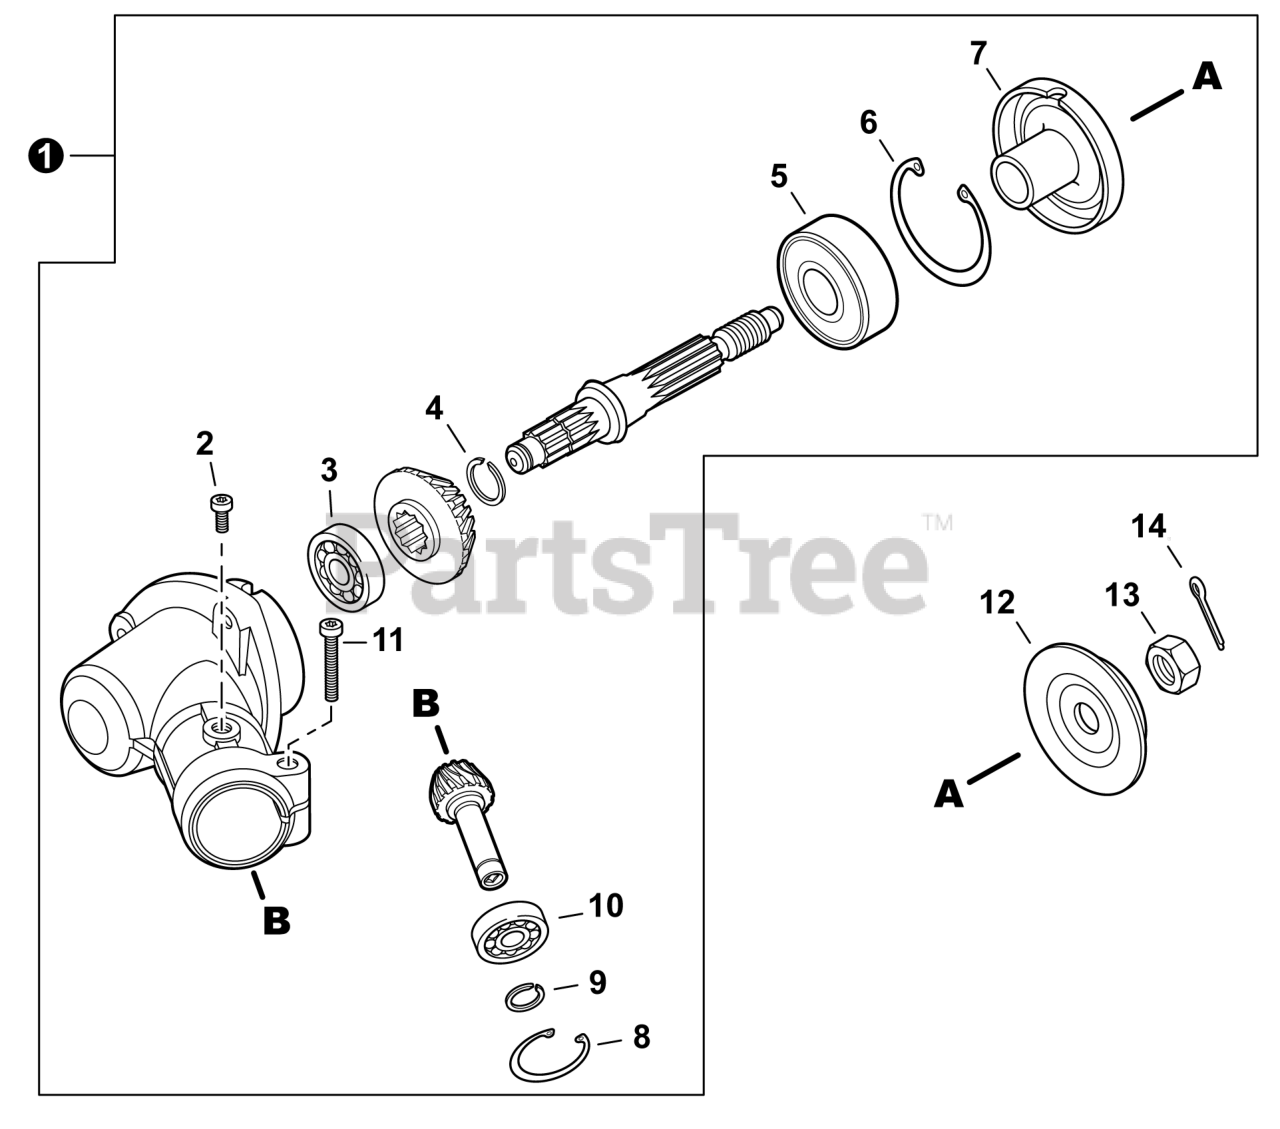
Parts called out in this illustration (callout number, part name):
1	GEAR CASE ASSY
2	BOLT, TORX 5x12
3	BEARING, BALL 609A
4	RING, SNAP 12
5	BEARING, BALL 6201 2RS
6	RING, SNAP 32
7	PLATE, ADAPTOR - UPPER
8	RING, SNAP 24
9	RING, SNAP 9
10	BEARING, BALL 609ZA
11	BOLT, TORX 5x25
12	PLATE, ADAPTOR - LOWER
13	NUT 10x1.25 LH
14	PIN, COTTER 2x22
